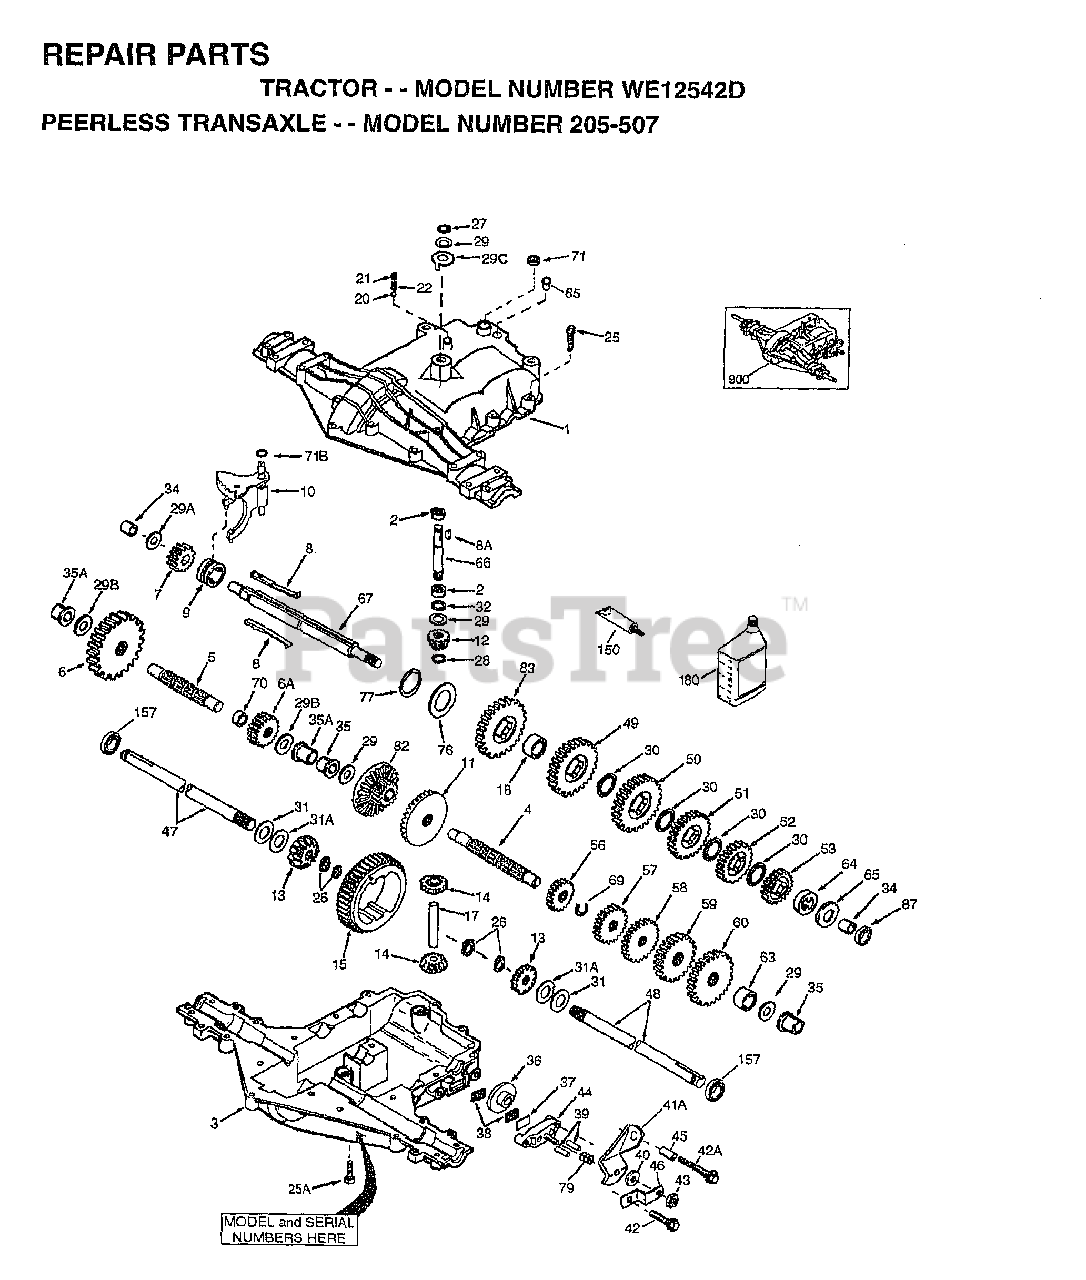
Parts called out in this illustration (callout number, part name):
1	TRANSAXLE COVER
2	NEEDLE BEARING 5/8" ID
3	TRANSAXLE CASE
4	COUNTERSHAFT
5	OUTPUT SHAFT
6	SPUR GEAR (38 TEETH)
6A	SPUR GEAR (15 TEETH)
7	SPUR GEAR (11 TEETH)
8A	PLUG, THRDED, 9/16-18
9	COLLAR, SHIFTER
10	SHIFT ROD & FORK
11	BEVEL GEAR (30 TEETH)
12	INPUT BEVEL PINION (13TEETH)
13	BEVEL GEAR (13 TEETH)
14	BEVEL PINION (13 TEETH)
15	RING GEAR (43 TEETH)
18	SPACER, NEUTRAL
20	BALL STEEL, 5/16" DIA.
21	SCREW, 3/8-16 X 3/8"
25A	SCREW 1/4-20 X 1-3/8"
26	RING RETAINER
27	RING, RETAINER
28	RETAINING RING
29	WASHER THRUST
29B	WASHER THRUST
29C	P/N CONFLICT - CHECK WITH SUPPLIER
30	WASHER THRUST
31A	FLAT WASHER
32	OIL SEAL 5/8"
34	BUSHING 9/16"
35	FLANGED BUSHING 5/8" ID
35A	FLANGED BUSHING 3/4"
37	PLATE BRAKE PAD
41A	BRAKE LEVER
42A	SCREW, 1/4-20 X 2-1/4
43	LOCKNUT 5/16-24
44	HOLDER BRAKE PAD
46	BRKT BRAKE LEVER
49	SPUR GEAR (29 TEETH)
50	SPUR GEAR (23 TEETH)
51	SPUR GEAR (19 TEETH)
52	SPUR GEAR (16 TEETH)
53	SPUR GEAR (15 TEETH)
56	SPUR GEAR (11 TEETH)
57	SPUR GEAR (17 TEETH)
58	SPUR GEAR (21 TEETH)
59	SPUR GEAR (24 TEETH)
60	SPUR GEAR (25 TEETH)
66	INPUT SHAFT
67	SHIFTER & BRAKE SHAFT
69	RETAINING RING
70	SPACER .890
71	SEAL SQUARE CUT
76	WASHER, THRUST
77	INVERTED RETAINING RING
82	BEVEL & SPUR GEAR (30 & 13 TEETH)
83	SPUR GEAR (27 TEETH)
85	OIL FILL PLUG
87	OIL SEAL 9/16"
150	LIQUID GASKET RTV SILICONE
157	OIL SEAL 3/4"
180	GEAR OIL 80W90
